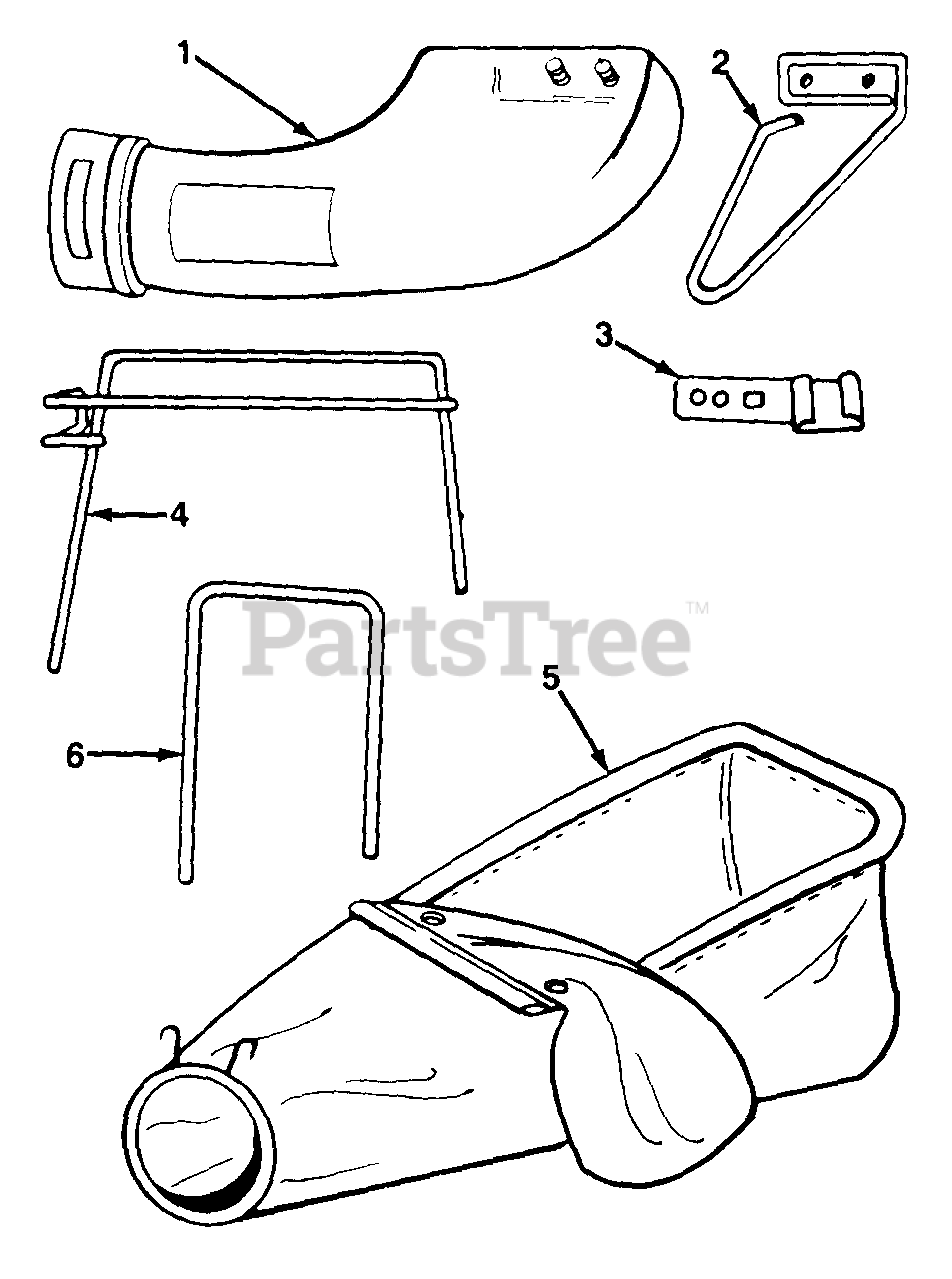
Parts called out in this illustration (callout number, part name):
1	Plastic Chute
2	Chute Mounting Bracket w/Wire
3	Handle Bracket
4	Bag Frame
5	Bag w/Clamp Ring
6	Upper Support Tube
